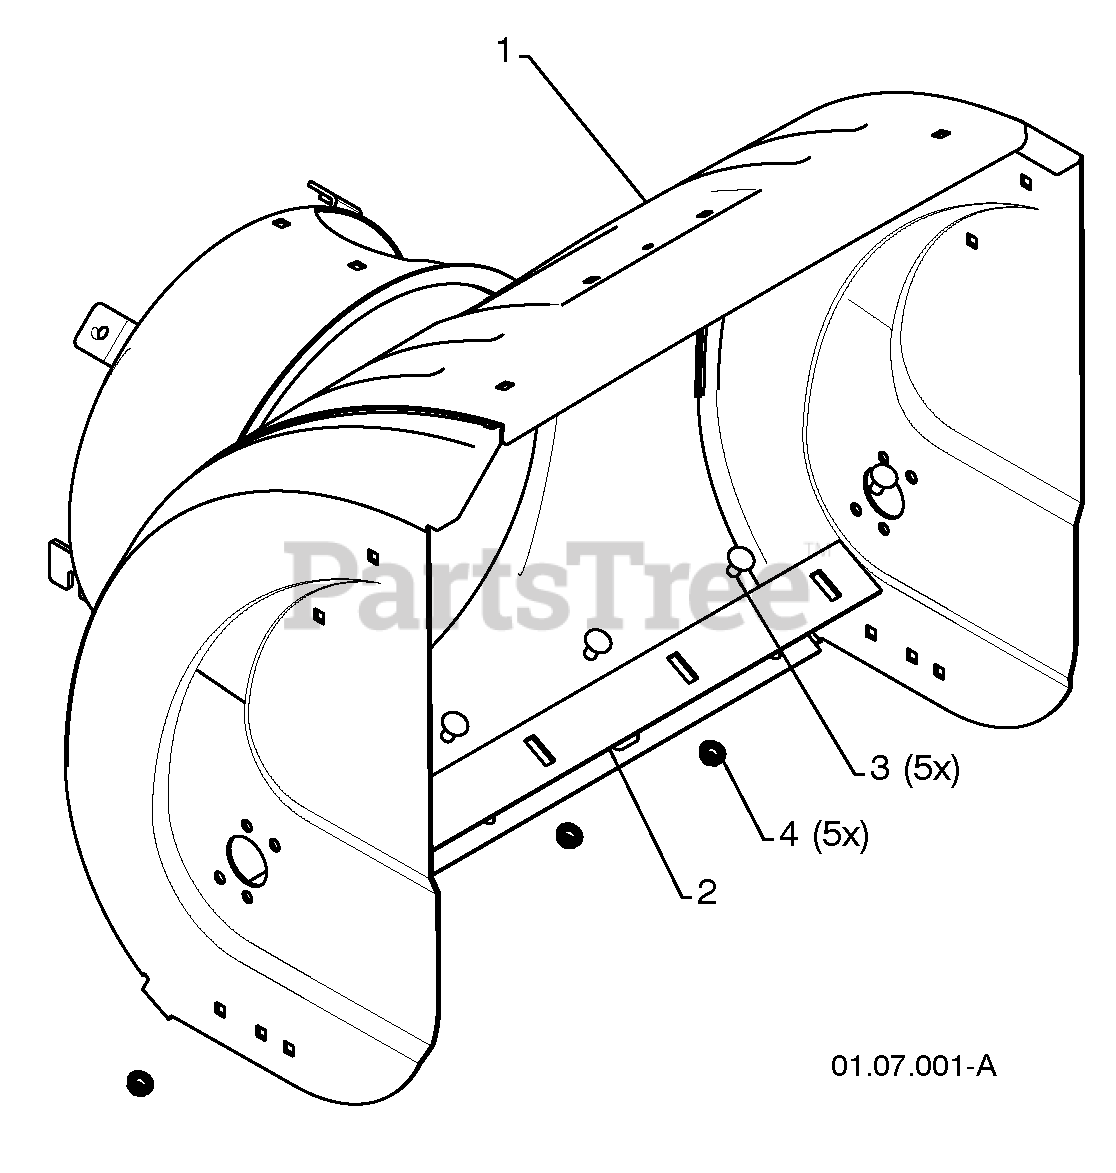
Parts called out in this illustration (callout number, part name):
1	AUGER HOUSING
2	SCRAPPER BAR
3	CARRIAGE BOLT 5/16-18 X .625
4	NUT 5/16-18
